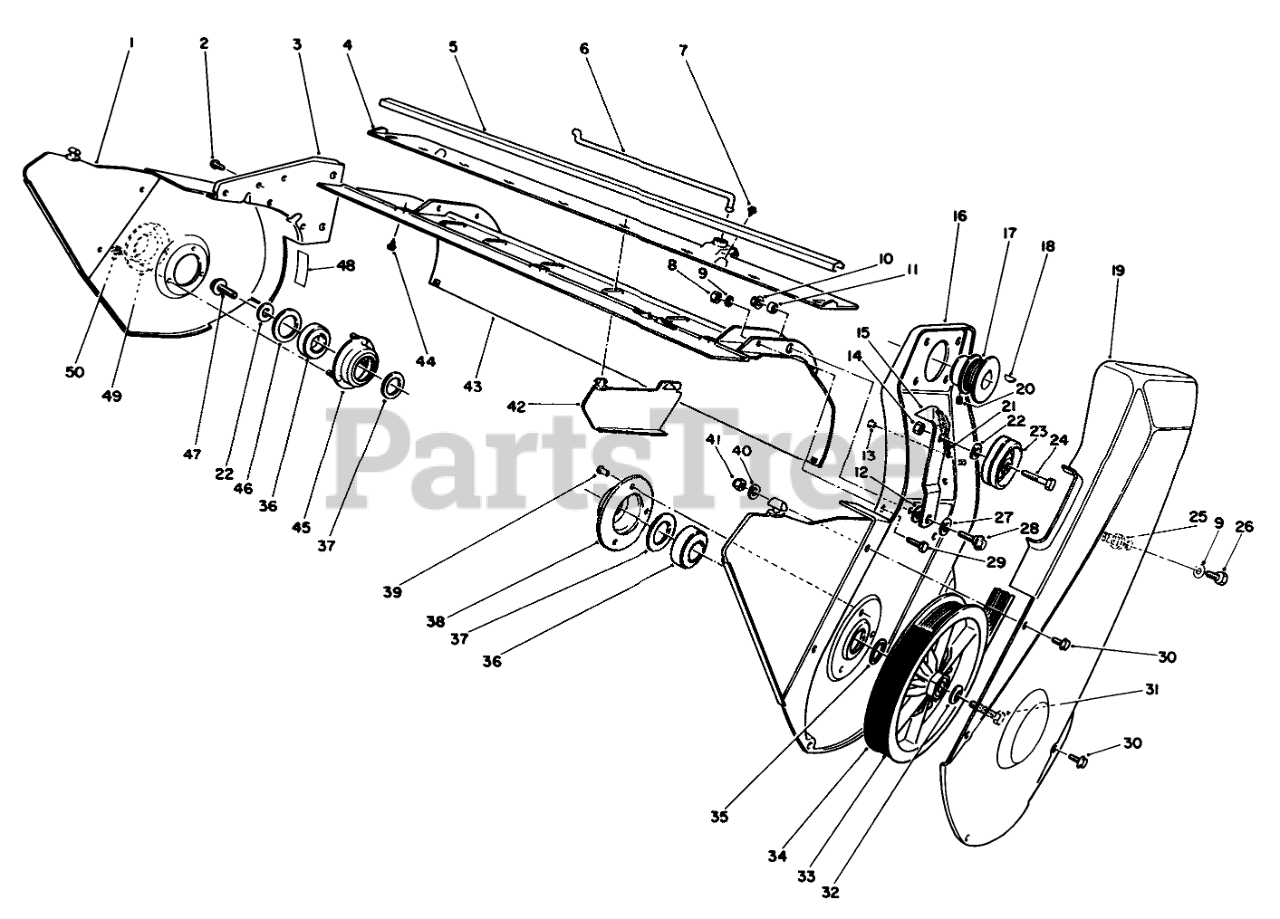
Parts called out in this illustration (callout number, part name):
1	OUTSIDE VANE
2	SCREW-HWH
3	Plate-R.H. Side
4	Mount-Vane
5	Moulding
6	VANE ADJ LINKAGE
7	10-16 X 3/8 THDG SCREW
8	NUT-LOCK, CONE
9	WASHER-FLAT
10	NUT-HF
11	SPACER
12	WASHER-PIVOT
13	Eyelet
14	NUT-LOCK, NI
15	IDLER ARM
16	Plate-L.H. Side
17	Pulley
18	KEY-WOODRUFF
19	Cover-Drive
20	SCREW-HSH
21	IDLER SPRING
22	WASHER-FLAT
23	IDLER PULLEY
24	SCREW-HH
25	PLASTIC GROMMET
26	SCREW-HWH
27	WASHER
28	SCREW-SHOULDER
29	SCREW-HH
30	SCREW-SHWH
31	SCREW-HH
32	WASHER-BELLEVILLE
33	BELT - DRIVE
34	ROTOR PULLEY ASY
35	WASHER
36	BEARING-BALL
37	WASHER-THRUST
38	FLANGE-BEARING
39	RIVET
40	WASHER-FLAT
41	NUT-LOCK, NI
42	CENTER VANE
43	Housing
44	SCREW-HWHTF
45	FLANGE-BEARING
46	WASHER-RUBBER
47	SCREW-HHF
48	Decal
49	Trough
50	NUT-CAP
